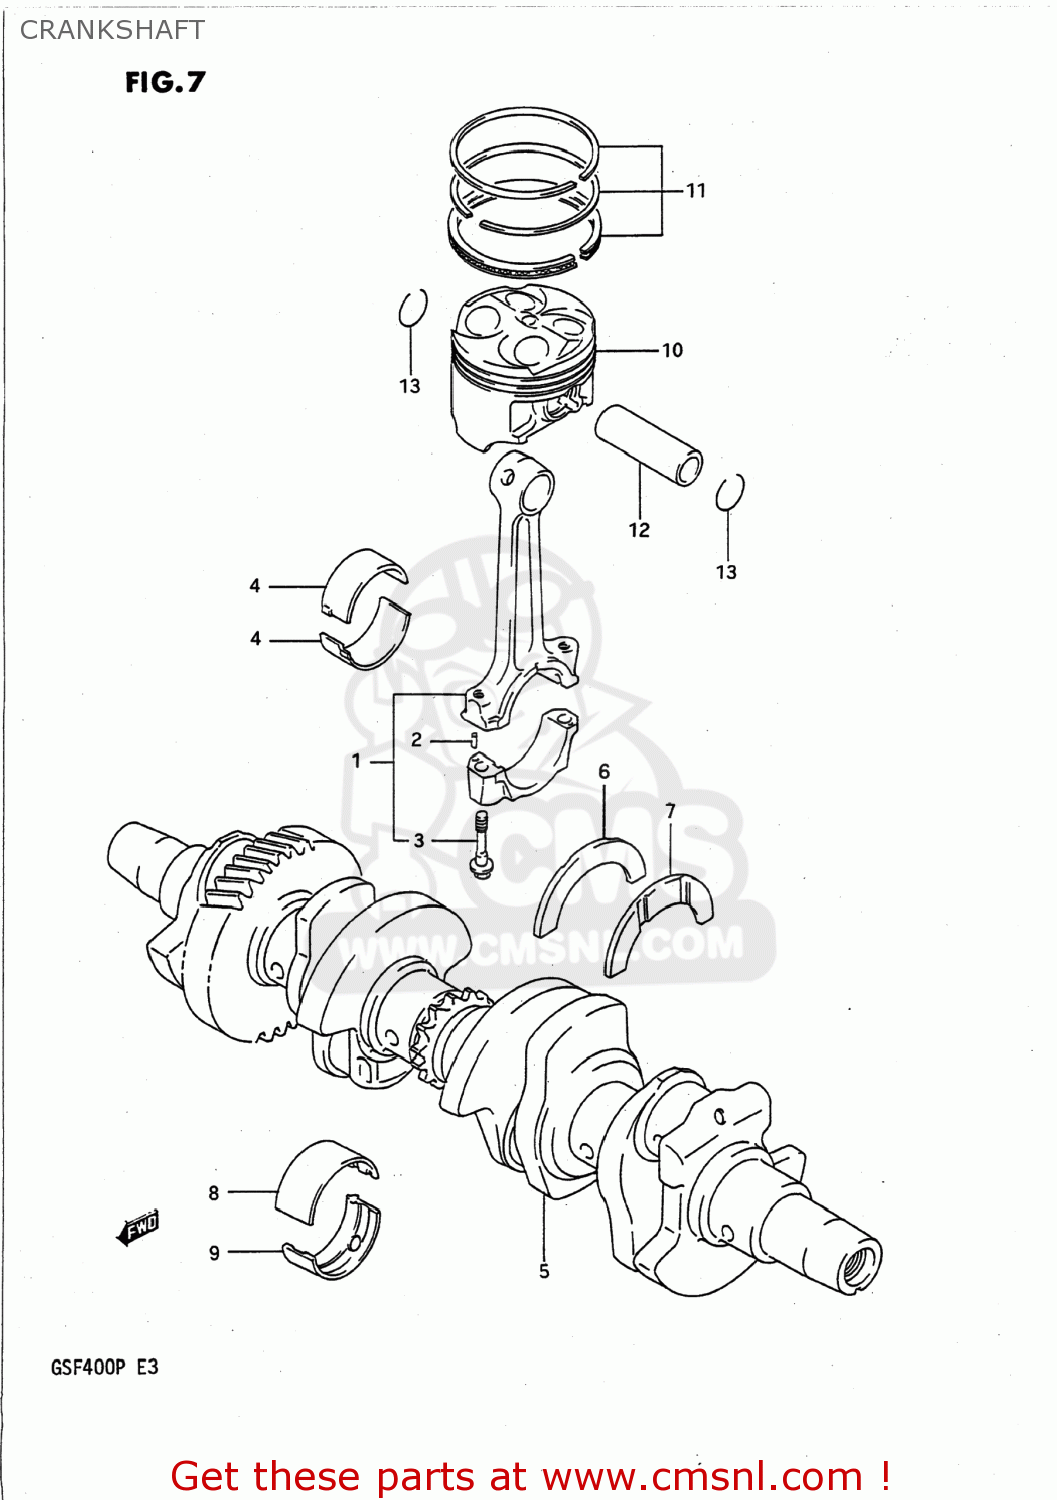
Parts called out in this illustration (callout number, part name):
1	CONNECTING ROD ASSY
2	PIN
3	BOLT,CONNECTING ROD
4	BEARING,CRANK PIN
5	CRANKSHAFT SET
6	PLATE,CRANK THRUST
7	PLATE,CRANK THRUST
8	BEARING,CRANKSHAFT UPR
9	METAL CRANKSHAFT,LOWER
10	PISTON
11	RING SET,PISTON
12	PIN,PISTON
13	RING,SNAP 16MM
